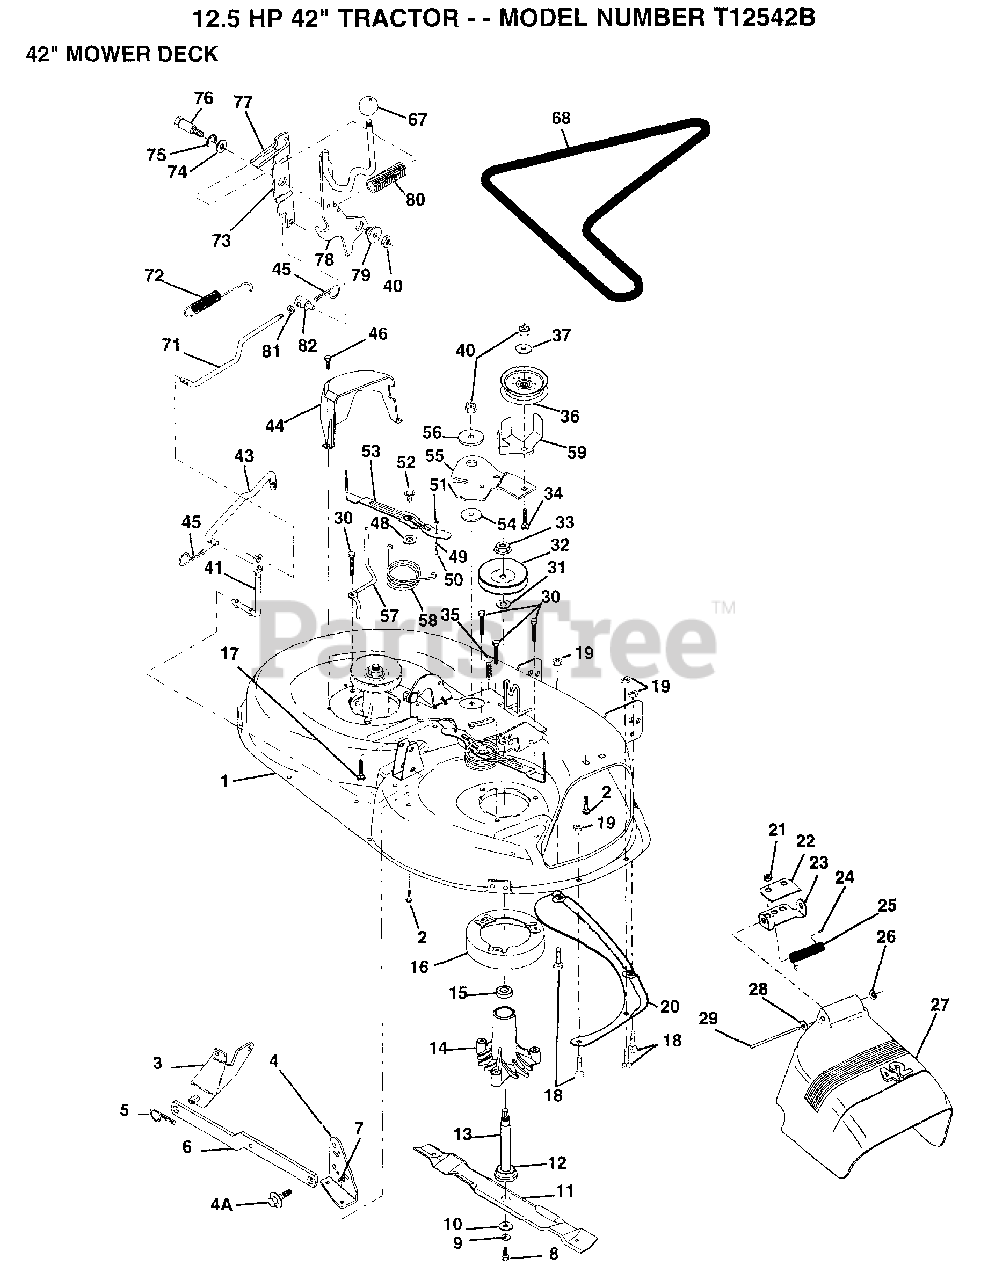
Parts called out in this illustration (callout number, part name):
2	BOLT
3	BRKT ASM SWAY BAR
4	BRKT DECK SW BAR
4A	BOLT SHD 5/16-18
7	NUT
8	BLADE BOLT
10	WASHER.HARD.BLADE
11	"BLADE.42"" MULCHER"
12	BEARING.BALL
14	HSG ASM MANDREL
15	BEARING
17	BOLT RDHD 3/8-16
18	BOLT
19	NUT
21	NUT
22	STIFFENER BRKT
23	DEFLECTOR BRKT
24	CAP-SLEEVE LT
25	SPRING TORSION
26	NUT PUSH M
27	DEFLECTOR.SHIELD
28	WASHER
29	HINGE ROD
31	WASHER
34	BOLT
35	XMAS TREE FASTNER
36	FLAT IDLER PULLEY
37	WASHER
40	NUT
41	PIVOT ROD
43	ROD CLUTCH W/NIBS
44	GUARD MAND LH BLK
45	RETAINER M
46	SCREW.1/4-20X5/8
48	HARD SMALL WASHER
50	SHOULDER BOLT
51	LOCKNUT
52	BOLT.SHLD.5/16-18
53	BRAKE PAD ARM ASM
54	HARDENED WASHER
56	SPACER RETAINER
57	KEEPER BELT LH 42
58	SPRING TORSN BRAK
59	GUARD IDLER TUV
67	CONTROL KNOB LT
68	BELT-V MWR 82.625
71	ROD CLUTCH 38/42
72	RETURN SPRING
73	CLUTCH ARM SECOND
74	WASHER
75	RING
76	SHOULDER BOLT
77	SPRING KEEPER
78	LEVER ASM CLT PRM
79	BUSHING
81	NUT
82	TRUNION ADJ
